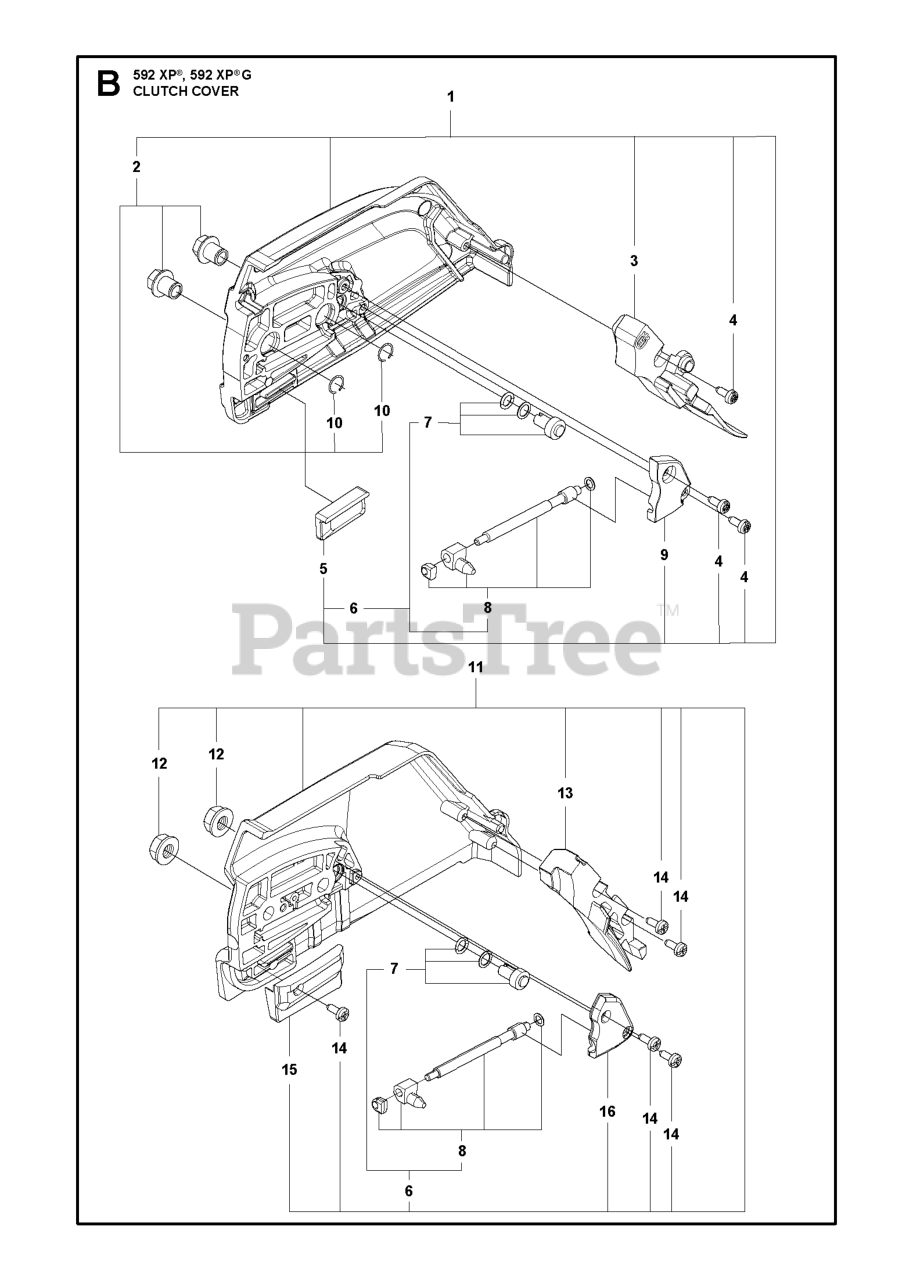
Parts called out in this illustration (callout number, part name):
1	CLUTCH COVER ASSY STANDARD REW
2	CHAIN BRAKE KIT UNLOSABLE NUTS
3	CHIP GUARD
5	CHAIN GUIDE
6	CHAIN TENSIONER KIT H565/H572
7	WORM WHEEL KIT H565/H572
8	WORM SCREW KIT H565/H572
9	COVER WORM SCREW
10	SNAP RING SNAP RING 12X10X1
11	Covers
12	NUT M8 FLANGE
13	PROTECTOR
14	SCREW CITXPANT
15	CHAIN GUIDE
16	COVER
